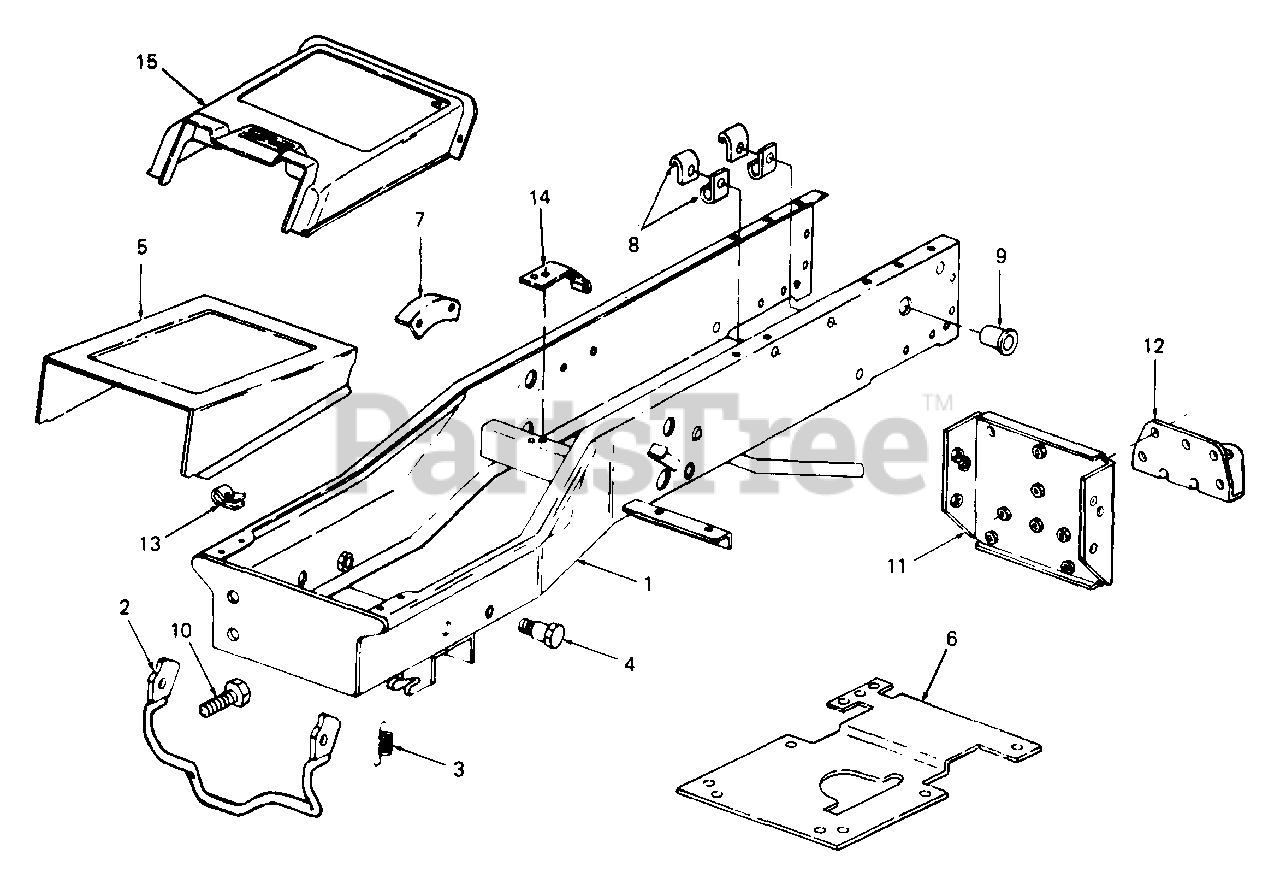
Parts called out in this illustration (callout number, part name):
3	Spring, Latch
4	Bolt, Shoulder
5	Cover, Frame w/Graphic
6	Baffle, Lower Frame
7	Bracket, Height Indicator
8	Clip, Cable
9	Bushing, Snap
10	Screw, Adjustment, 1/2-20 x 1.0 Lg GR5
13	Nut, Speed
14	Bracket, Switch
15	Cover, Frame
